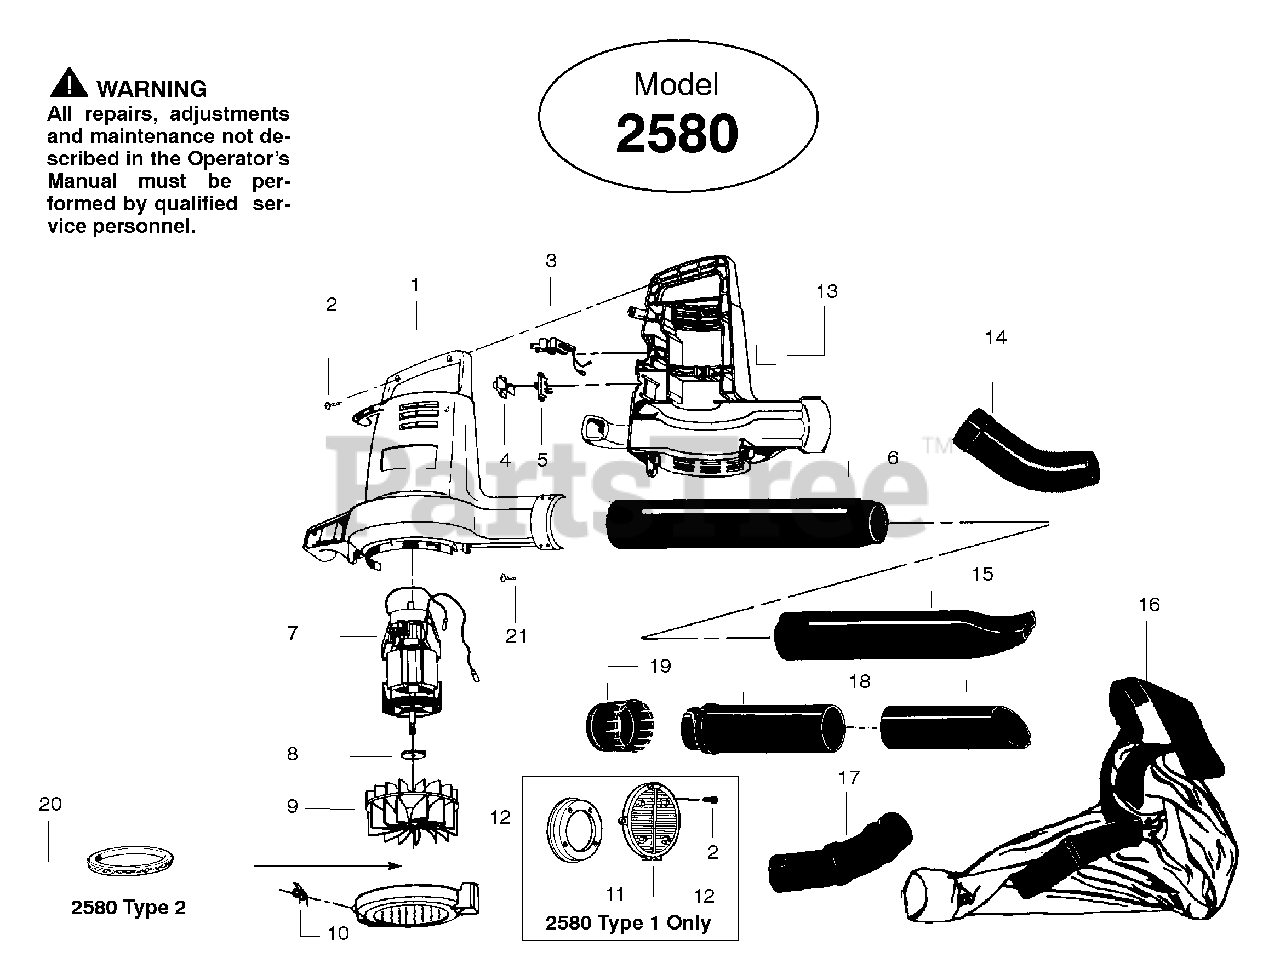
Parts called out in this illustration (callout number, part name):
1	Housing Set Type 1, 2, 3
1	Housing Set Type 4
3	Wire Harness Type 1 & 2
3	Wire Harness Type 3 & 4
4	Switch Cover
5	Switch Type 1 & 2
5	Switch Type 3 & 4
6	Blower Tube Type 1-3
6	Blower Tube Type 4
7	Motor Ass'y. 2580 Type 1 & 2
7	Motor Ass'y. 2580 Type 3 & 4
9	Impeller
11	Inlet Baffle - Type 1
12	Inlet Cover
14	Concentrator Nozzle Type 1, 2 & 3
14	Concentrator Nozzle Type 4
15	Nozzle Type 1-3
15	Nozzle Type 4
16	Vacuum Bag Kit Type 1, 2 & 3
16	Vacuum Bag Kit Type 4
17	Elbow (Type 1,2,3)
18	Vacuum Tube Kit
19	Funnel (Type 2)
20	Inlet Orifice (Type 2)
21	Screw (Type 4)
